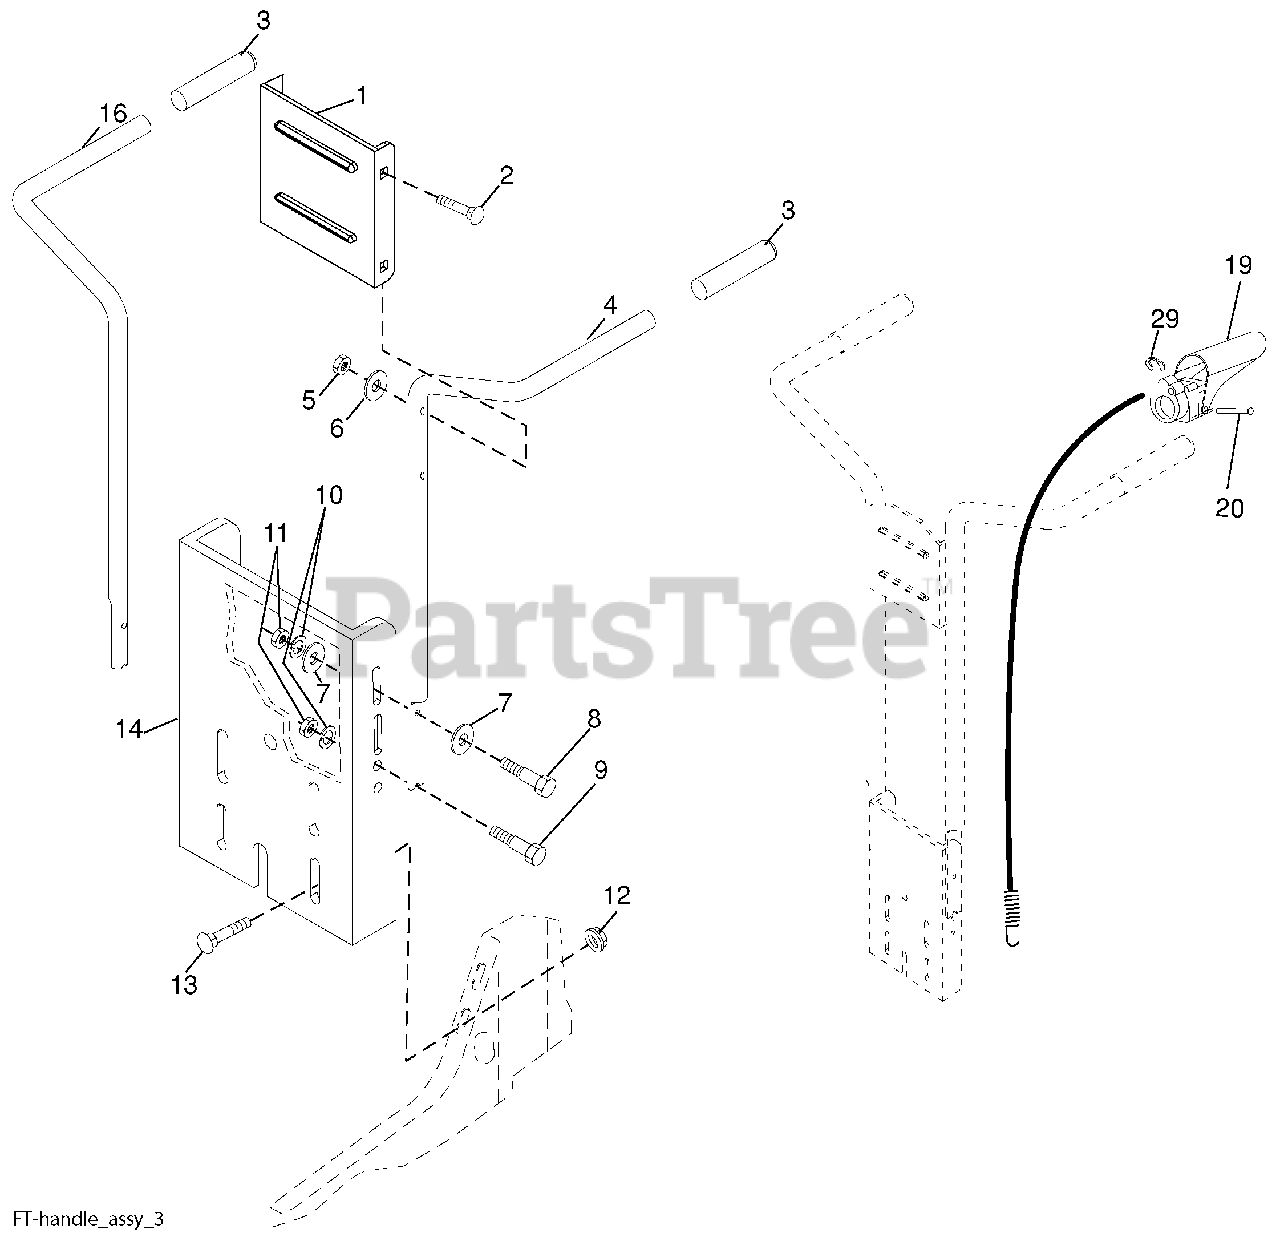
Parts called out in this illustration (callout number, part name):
1	Bracket, Handle
2	Bolt, Carriage 5/16-18 x 1-1/2
3	Grip, Handle
4	Handle, L.H.
5	Nut, Hex, Crownlock 5/16-18
6	Washer 11/32 x 11/16 x 16 Ga.
7	Washer 3/8 x 7/8 x 14 Ga.
8	Bolt, Hex Head 5/16-18 x 1-1/4
9	Bolt, Hex Head 5/16-18 x 1
10	Washer, Lock 5/16
11	Nut, Hex 5/16-18
12	Nut, Hex, Flanged 5/16-18
13	Bolt, Carriage, Gr. 5 5/16-18 x 3/4
14	Panel, Handle
16	Handle, R.H.
19	Tine Control Lever Assembly
20	Pin, Pivot
29	Retaining Ring
